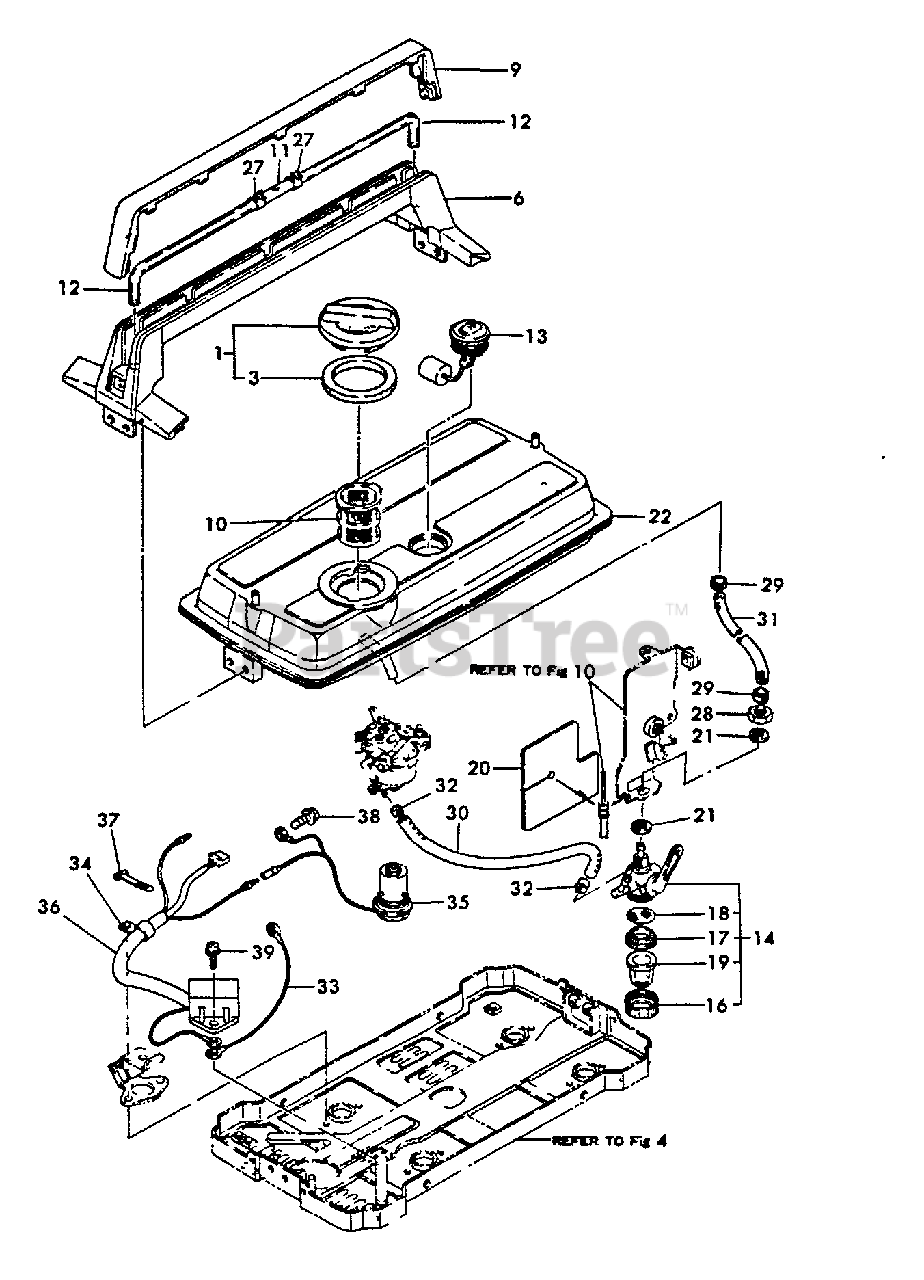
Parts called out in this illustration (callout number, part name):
1	CAP ASSY, FUEL TANK
3	GASKET, CAP
6	GRIP ASSY, FUEL TANK
9	CAP, GRIP
10	FILTER, FUEL
11	JOINT
12	HOSE
13	GAUGE, FUEL
14	COCK ASSY, FUEL
16	RETAINER
17	GASKET
18	FILTER, FUEL
19	BOWL, STRAINER
20	COVER
21	GASKET
22	TANK ASSY, FUEL
27	CLAMP
28	LOCKNUT - 12
29	CLAMP, HOSE
30	PIPE, FUEL
31	PIPE, FUEL
32	CLAMP, HOSE - 10
33	WIRE A
34	CLAMP
35	SENSOR, OIL LEVEL
36	UNIT, OIL SENSOR
37	CLAMP
38	SCREW 6×12
39	SCREW 6×12
